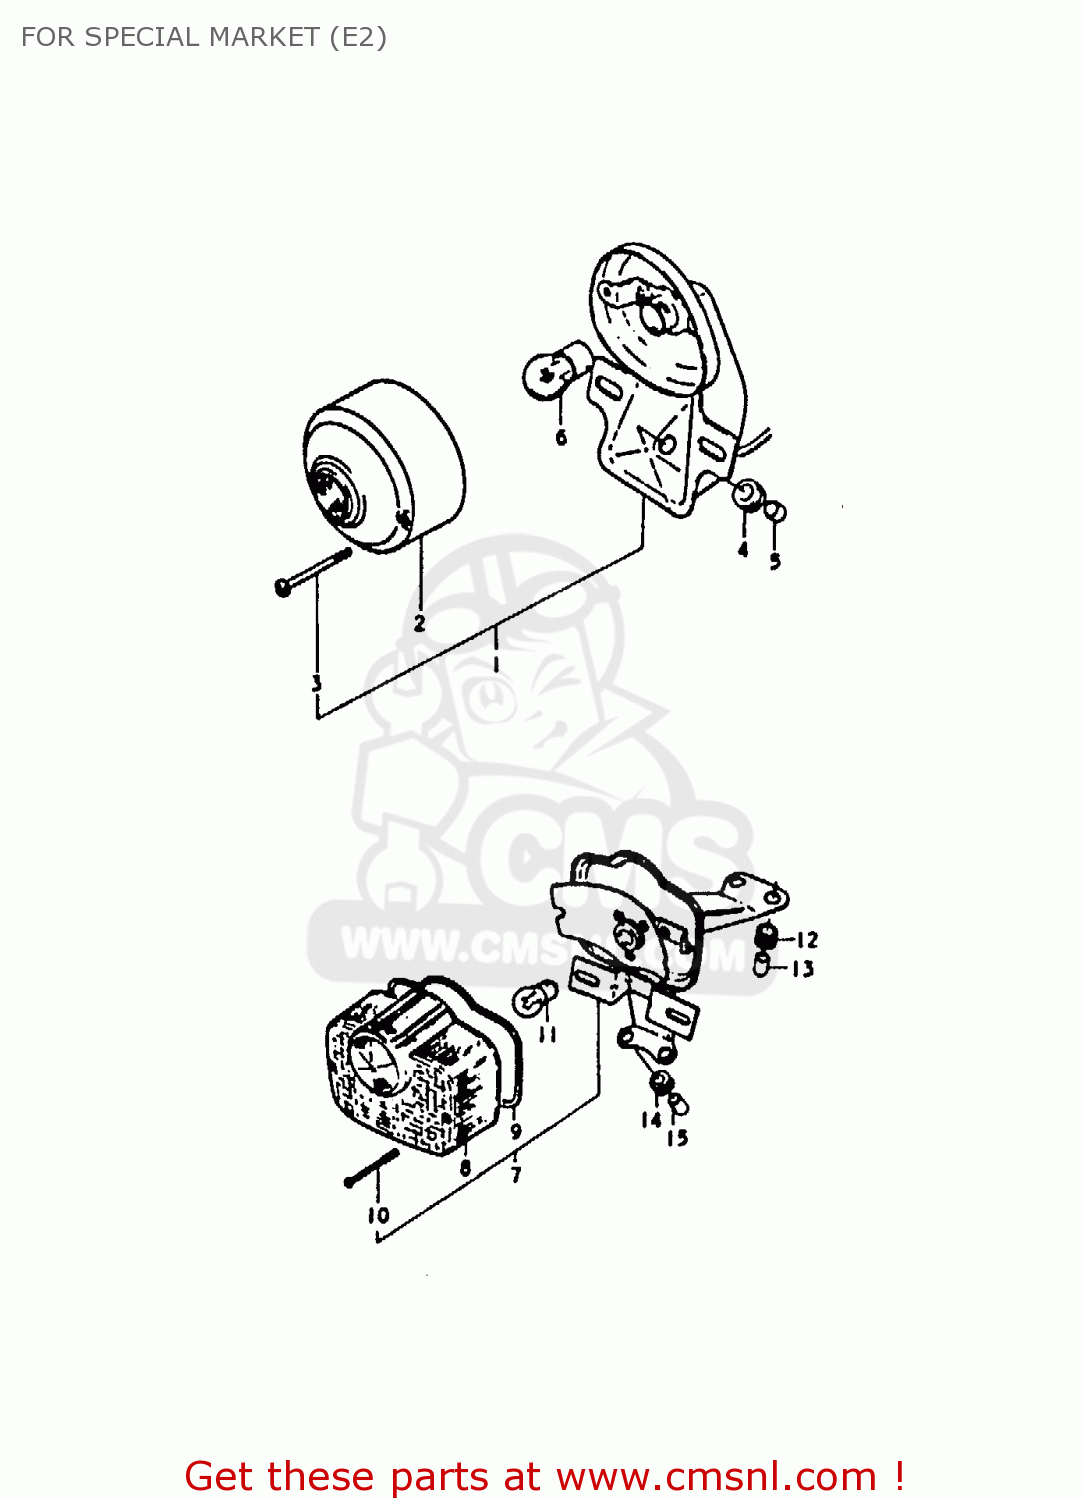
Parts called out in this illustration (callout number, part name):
1	SCREW
2	LOCK WASHER
3	GASKET,FLOAT CHAMBER (NAS)
4	FLOAT
5	PIN,FLOAT
6	SPRING,THROTTLE STOP SCREW
7	SCREW,PILOT AIR
8	SPRING
9	VALVE ASSY,NEEDLE
10	WASHER
11	NEEDLE,JET
12	GASKET,NEEDLE VALVE (NAS)
13	CLIP,NEEDLE
14	PLUNGER,STARTER
15	SPRING
16	CAP,STARTER PLUNGER
17	VALVE,THROTTLE
18	SPRING,THROTTLE VALVE
19	STOPPER,NEEDLE CLIP
20	ROD,THROTTLE VALVE ADJUST
21	CAP,THROTTLE VALVE STOP SCREW
22	SCREW,THROTTLE STOP
23	PIN 12X10
24	ADJUSTER,CABLE
25	NUT
26	PLUG
27	GASKET,DRAIN,PLUG (NAS)
28	JET,MAIN
29	JET,PILOT
30	JET,NEEDLE
31	JET,MAIN
32	JET,PILOT
